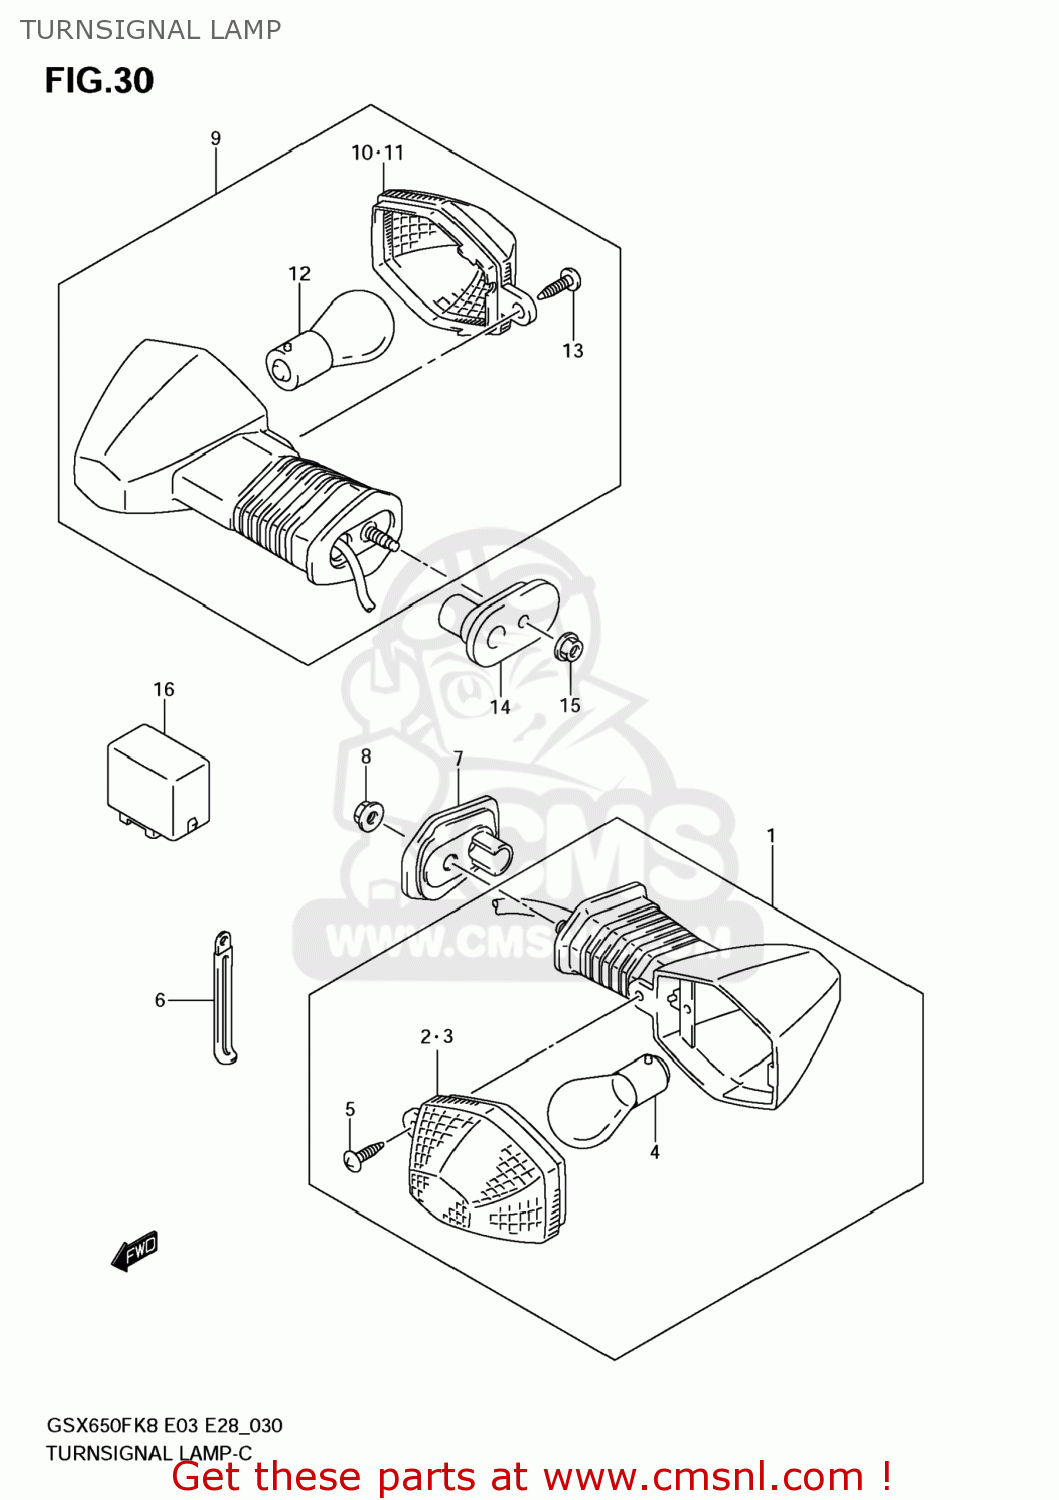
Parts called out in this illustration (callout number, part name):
1	LAMP ASSY,FR TURN SIGNAL,R
2	LENS
3	LENS
4	BULB(12V21W,AMBER)
5	SCREW
6	CLAMP(L:45)
7	PLATE,FR TURNSIGNAL
8	NUT
9	LAMP ASSY,RR TURNSIGNAL,R
10	LENS
11	LENS
12	BULB(12V21W,AMBER)
13	SCREW
14	PLATE,TURNSIGNAL LAMP
15	NUT
16	RELAY ASSY,TURNSIGNAL LAMP
